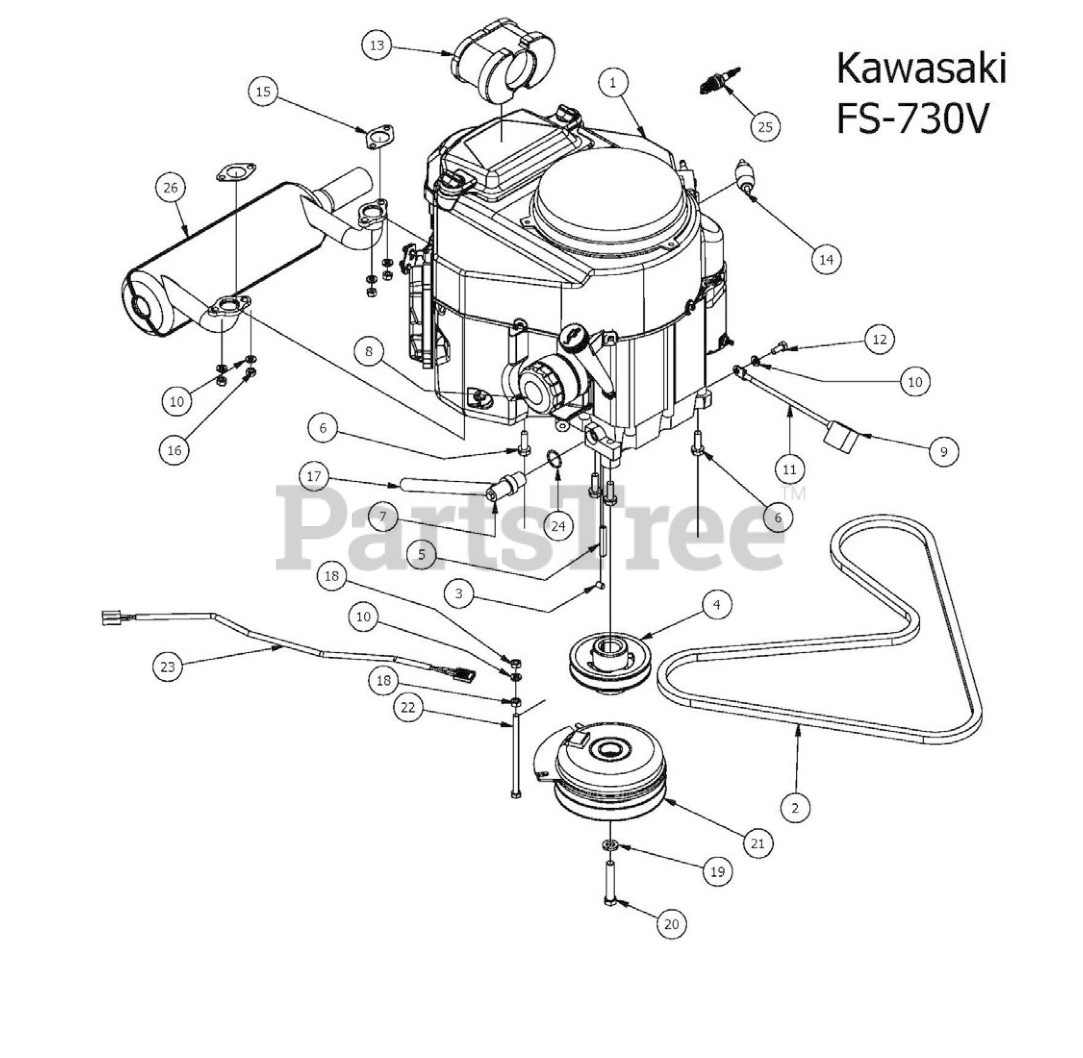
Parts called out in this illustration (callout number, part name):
1	FS730V Engine
2	75.8 Pump Belt
3	5/16 Set Screw
4	3/4 Motor Pulley
5	1/4 x 2 Square key Stock
6	3/8 x 1 1/8 bolt
8	Kawasaki Oil Filter
9	Black Boot For Ground Cable
10	5/16" Lock Washer
11	Ground Cable
12	M8x1.20x20MM Hex head bolt
13	Kawasaki Air Filter
14	Universal Inline Fuel Filter
15	Exhaust Gasket
16	M8-1.25 Zinc Nut
17	1/2 Clear Braded Hose Priced/Foot
19	7/16" Lock Washer
20	7/16" x 2 1/2" Hex Bolt
21	Clutch Assembly
22	5/16-18 x 5-1/2 GR 5 Hex Bolt
23	Clutch Pigtail
25	Spark Plug - Kawasaki
26	Kawasaki Muffler 1251
